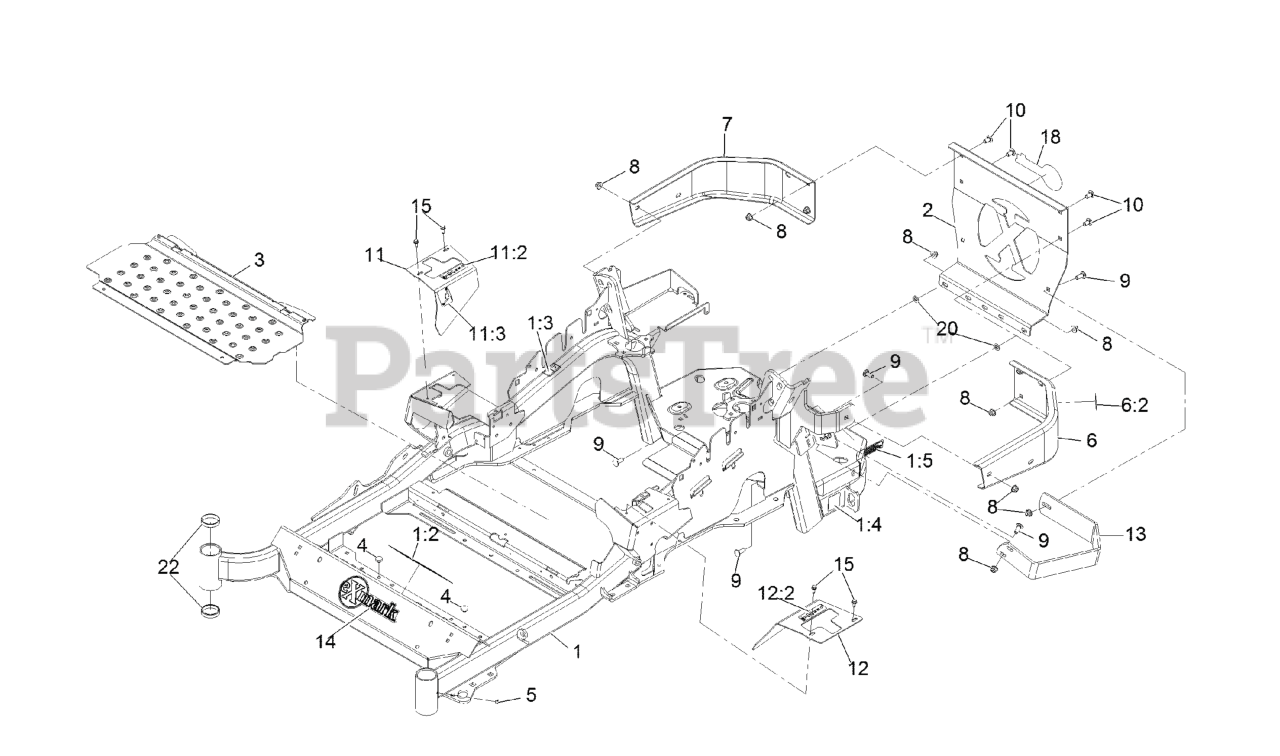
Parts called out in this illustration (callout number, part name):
1	MAINFRAME ASM
1:2	DECAL-DANGER
1:3	DECAL-WARNING
1:4	DECAL-HAZARD, PINCHED FINGER
1:5	DECAL-ARRESTOR, SPARK
2	PLATE,REAR GUARD
6	LH BUMPER ASM
6:2	DECAL-WARNING
7	BUMPER-RH
8	NUT-HF, NI
9	SCREW-CARR
10	SCREW-CARR
11	RH MOTION CONTROL COVER ASM
11:2	DECAL-CONTROL, MOTION
11:3	DECAL-PARK BRAKE, CE
12	LH MOTION CONTROL COVER ASM
12:2	DECAL-CONTROL, MOTION
13	GUARD-MUFFLER
14	DECAL-EXMARK
15	SCREW-HWH
20	NUT-PUSH
22	CUP-BEARING
